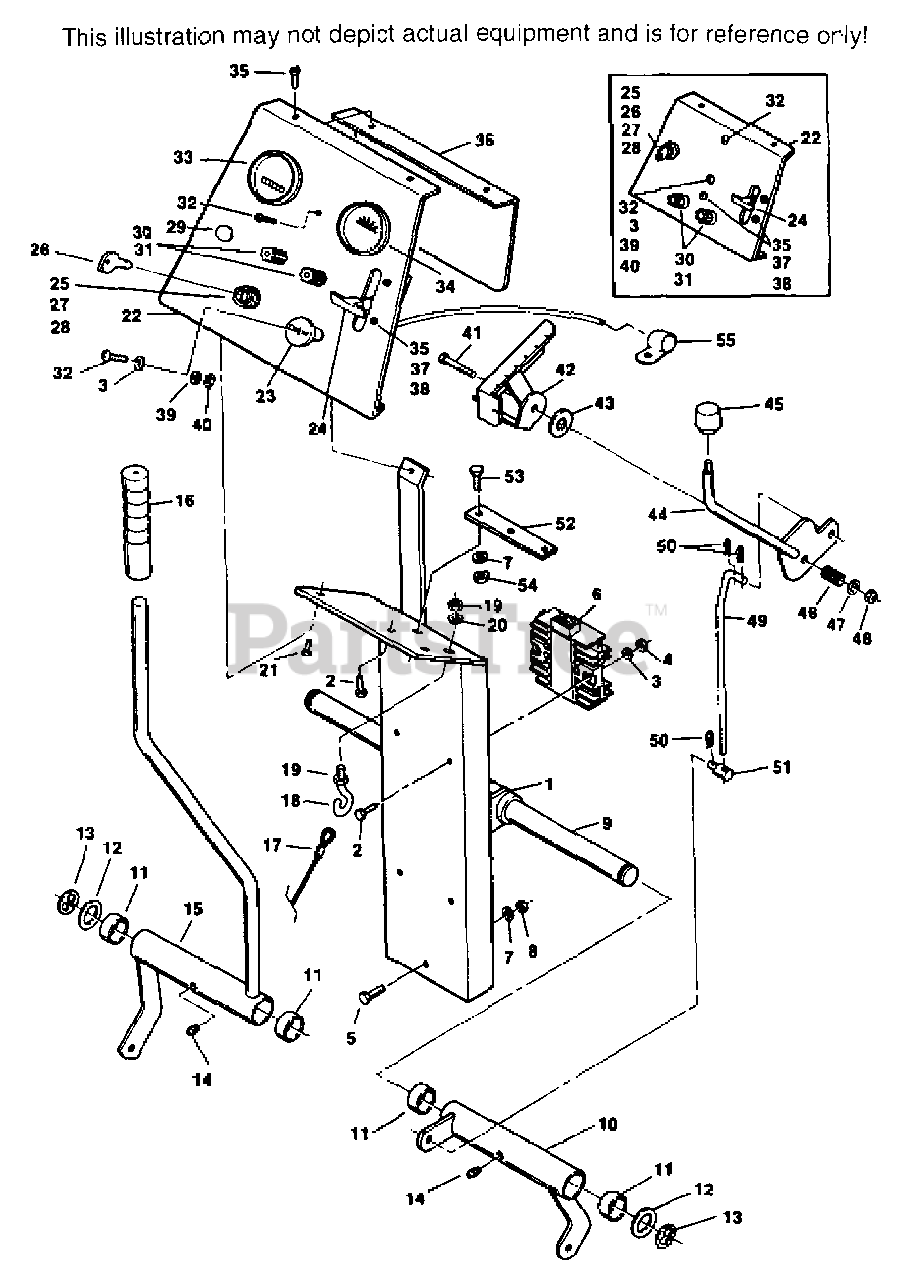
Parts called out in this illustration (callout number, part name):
1	CONSOLE SUPPORT WLD
3	WASHER, 9/32 X 5/8 X 16 GA.
7	LOCKWASHER, 5/16 SPRING
9	BELL CRANK SHAFT
10	SHIFTER WLD.(INCL. 11 & 14)
11	BRONZE BEARING
12	WASHER, 49/64 X 1-1/4 X 16 GA.
13	RETAINING RING, 3/4 EXT."E"
14	GREASE FITTING, 1/4-28 STR.
15	MOWER ENGAGE WLD.(INCL. 11, 14, 16)
16	GRIP, MOWER LEVER
17	WINCH CABLE ASSEMBLY
18	EYEBOLT, 3/8-16 X 2
20	LOCKWASHER, 3/8 SPRING
22	INSTRUMENT PANEL
24	THROTTLE CONTROL
25	STARTER SWITCH(INCL. 26-28)
26	KEY, IGNITION
27	LOCKWASHER, INT. TOOTH 5/8
28	HEX NUT, 5/8-11
30	FUSE HOLDER
31	FUSE, 20A
36	PANEL COVER WLD.
39	LOCKWASHER, 1/4 SPRING
42	SHIFT QUADRANT WLD.
43	WASHER, 3/8 X 2 X 16 GA.
44	SHIFTER HANDLE WLD.
45	SHIFTER KNOB
46	SPRING
47	WASHER, 13/32 X 13/16 X 16 GA.
48	HEX NUT, 3/8-16 ELASTIC STOP
49	SHIFTER CONNECTOR ROD
50	HAIR PIN COTTER, LARGE
51	SWIVEL JOINT
52	WINCH CABLE ATTACHMENT
55	CLAMP, CABLE
